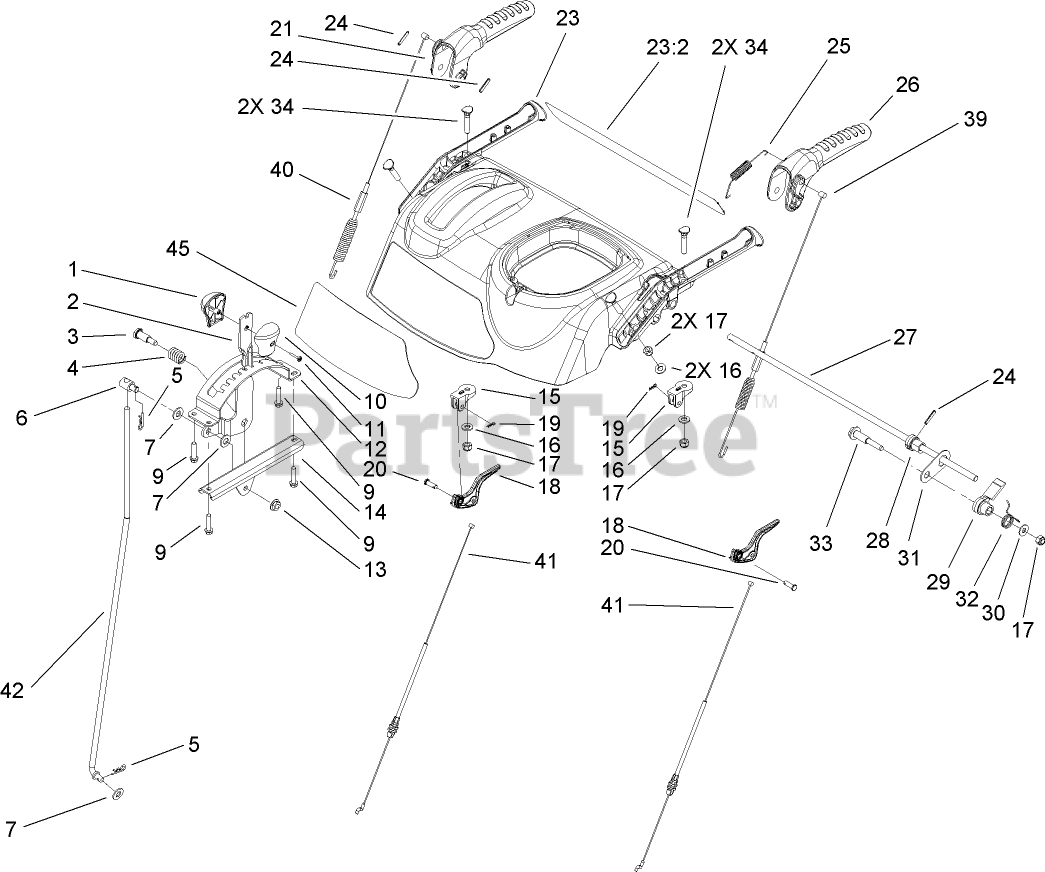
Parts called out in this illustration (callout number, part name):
1	KNOB-SHIFT, RH
2	SELECTOR-SPEED
3	SCREW-SHOULDER
6	TRUNNION-ROD
7	WASHER-FLAT
9	SCREW-PLASTITE
10	KNOB-SHIFT, LH
11	SCREW-PPH
12	GUIDE-SELECTOR, SPEED
13	NUT-HF
14	MOUNT-SELECTOR, SPEED
15	MOUNT-LEVER, CLUTCH
16	WASHER-FLAT
17	NUT-LOCK, NI
18	LEVER-CLUTCH
19	PIN-HAIR
20	PIN-CLEVIS
21	LEVER-AUGER
23	PANEL-CONTROL
23:2	DECAL-WARNING
24	PIN-SPRING
25	SPRING-TENSION
26	LEVER-TRACTION
27	ROD-LOCKOUT
28	CAM-LOCKOUT
29	LATCH-LOCKOUT
30	WASHER-FLAT
31	LINK-LOCKOUT
32	SPRING-TORSION
34	SCREW-HANDLE
41	CABLE-CLUTCH
45	DECAL-CONTROL PANEL
